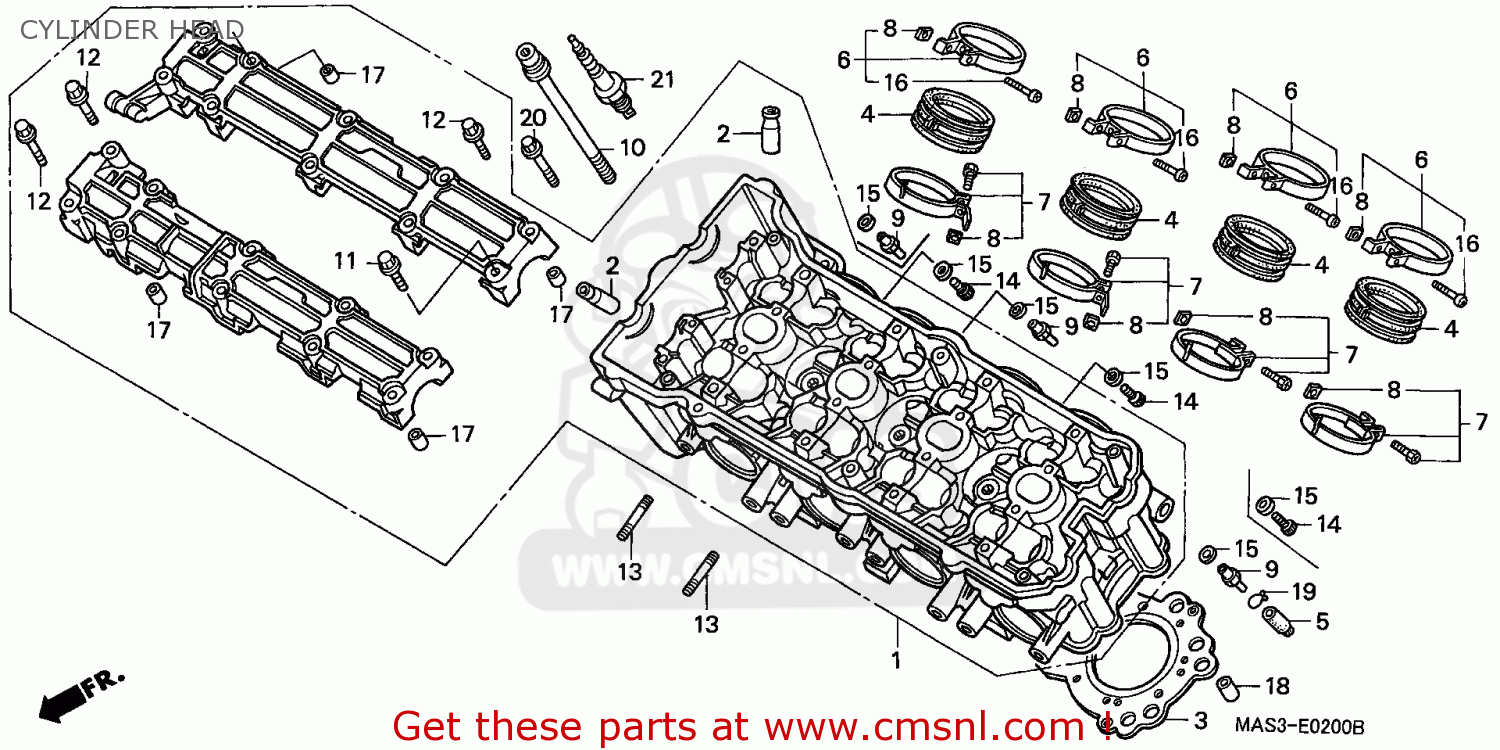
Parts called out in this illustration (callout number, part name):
1	HEAD ASSY,CYLINDE
2	GUIDE,VALVE(OUTER
3	GASKET,CYLINDER H (NAS)
4	INSULATOR,CARB
5	CAP,BOOST
6	BAND A,INSULATOR
7	BAND B,INSULATOR
8	NUT,SQUARE,5MM
9	JOINT,BOOST
10	BOLT,SOCKET 9X95
11	BOLT,FLANGE 6X37
12	BOLT,FLG.,6X45.5
13	BOLT STUD 8X24
14	BOLT,SOCKET,5X8
15	WASHER 5MM
16	SCREW, PAN, 5X32
17	PIN,DOWEL,8X20
19	CLIP B7,TUBE
20	BOLT,FLANGE,6X45
21	PLUG,SPARK(CR8EH9
